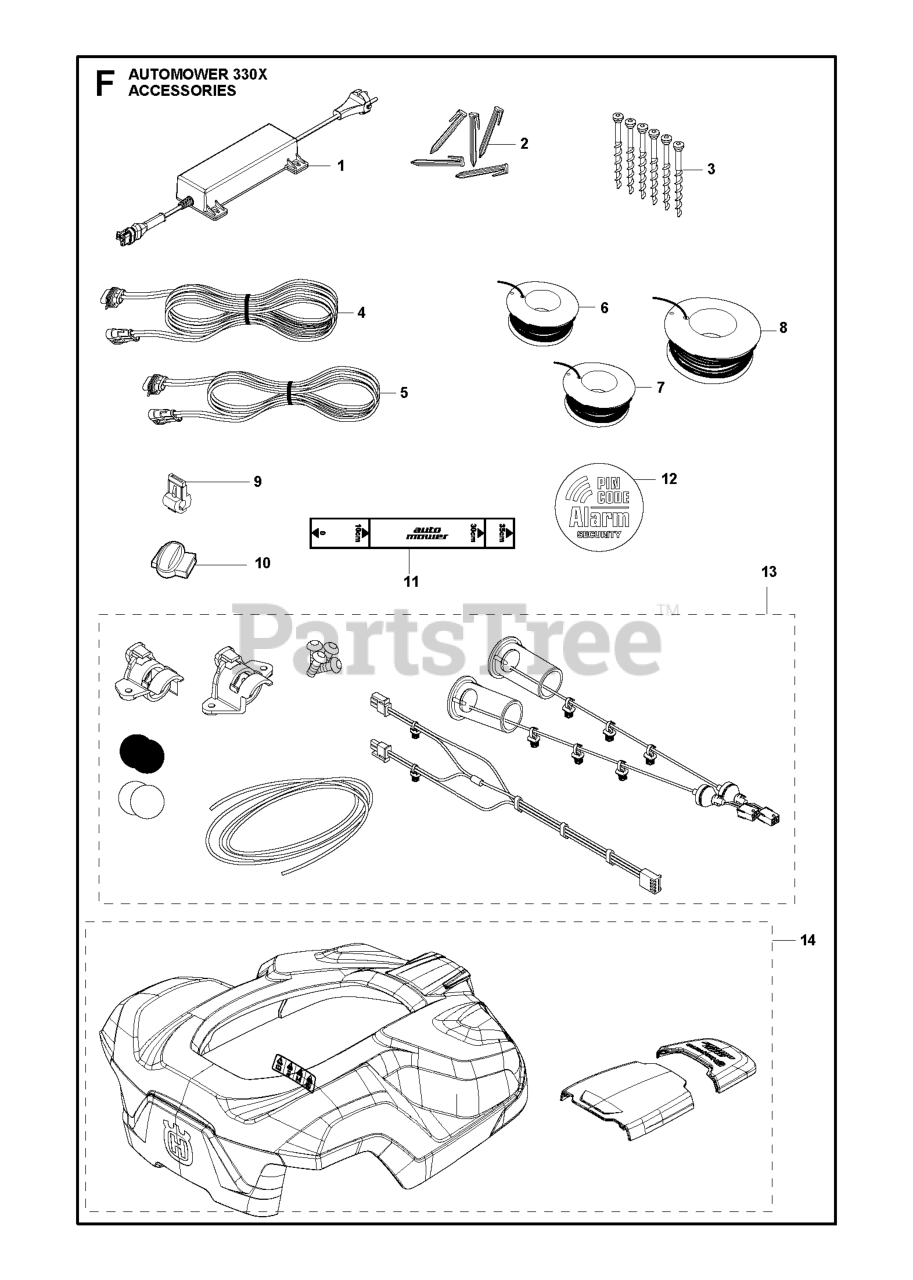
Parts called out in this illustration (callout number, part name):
1	POWER UNIT POWER SUPPLY TYPE F
2	STAPLE 100 PCS, BLISTER
2	STAPLE 100 PCS
3	SCREW 3 PCS, BLISTER PACK
3	SCREW KIT CS
4	LOOM LOW VOLTAGE CABLE 20 METE
5	LOOM LOW VOLTAGE CABLE 3 METER
5	LOOM LOW VOLTAGE CABLE 10 METE
6	WIRE 150M, BLISTER
6	WIRE BOUNDARY 150M
7	WIRE 250M
8	WIRE 500M
9	CONNECTOR 5 PCS, BLISTER
9	BRAKER
10	COUPLER SPLICER, 100 PCS
10	SPLICE KIT
10	COUPLER SPLICER, 5 PCS,
11	RULER / CENTIMETERS
12	LABEL SECURITY
